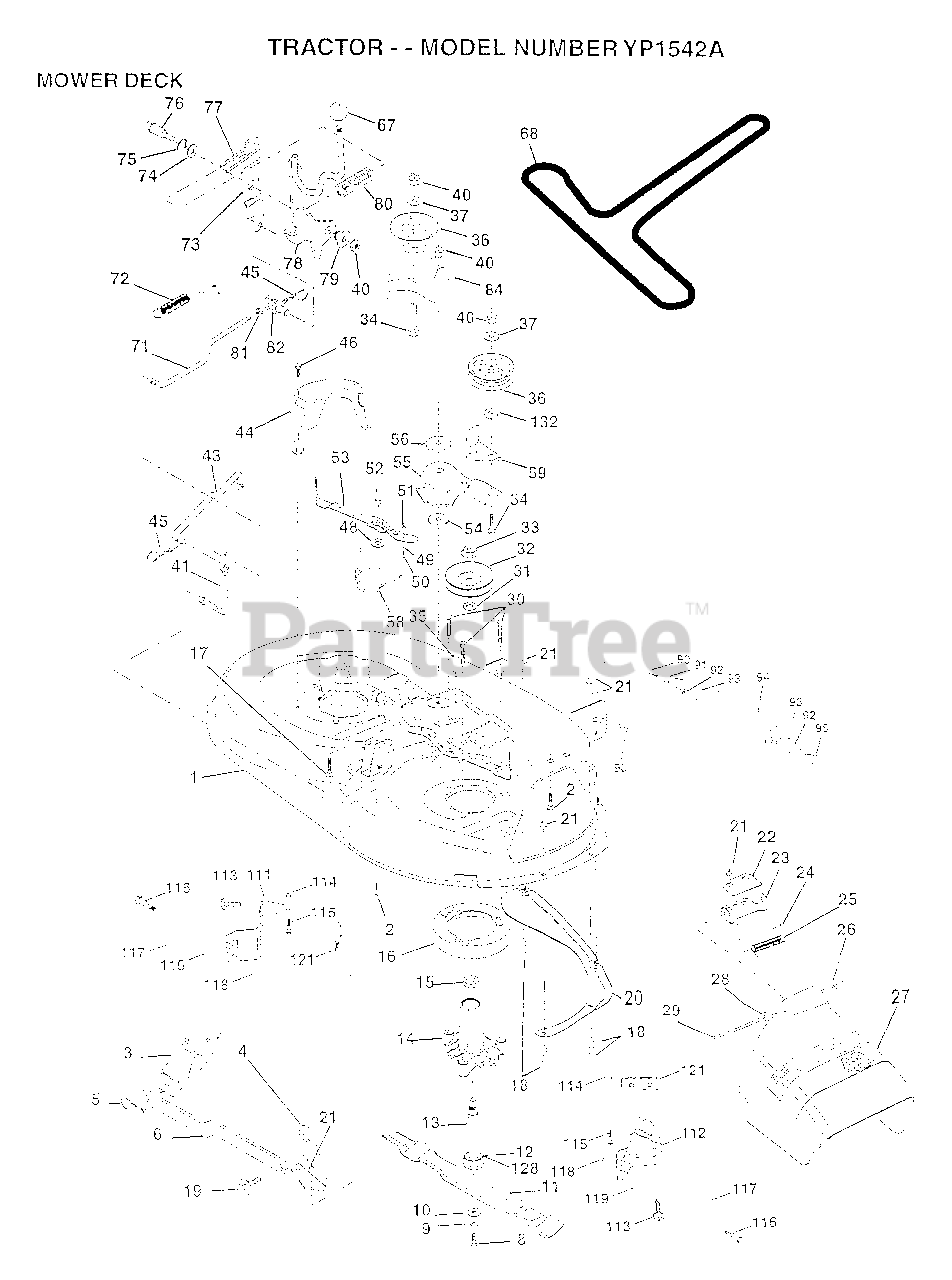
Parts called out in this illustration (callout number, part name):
1	DECK.WELD.42.
2	BOLT
3	BRKT ASM SWAY BAR
4	BRKT DECK SW BAR
8	BLADE BOLT
10	WASHER.HARD.BLADE
11	"BLADE.42"" HIPERF"
12	BEARING.BALL
14	HSG ASM MANDREL
15	BEARING
16	STRIPPER RND MWR
17	BOLT RDHD 3/8-16
18	BOLT
19	BOLT SHD 5/16-18
22	STIFFENER BRKT
23	DEFLECTOR BRKT
24	CAP-SLEEVE LT
25	SPRING TORSION
26	NUT PUSH M
27	DEFLECTOR.SHIELD
28	WASHER
29	HINGE ROD
31	WASHER
32	PULLEY.MANDREL.42
34	BOLT
35	XMAS TREE FASTNER
36	FLAT IDLER PULLEY
37	WASHER
41	PIVOT ROD
43	ROD CLUTCH W/NIBS
44	GUARD MAND LH BLK
45	RETAINER M
46	SCREW.1/4-20X5/8
48	HARD SMALL WASHER
49	ROLLER ASM-CAM
50	SHOULDER BOLT
51	LOCKNUT
52	BOLT.SHLD.5/16-18
54	HARDENED WASHER
55	ARM-IDLER
56	SPACER RETAINER
58	SPRING TORSN BRAK
59	GUARD IDLER TUV
67	KNOB.DUCKHEAD.1/2
68	BELT-V.SEC.46.KEL
71	ROD CLUTCH 38/42
72	RETURN SPRING
73	CLUTCH ARM SECOND
74	WASHER
75	RING
76	SHOULDER BOLT
77	SPRING KEEPER
78	LEVER CLUTCH ASM
79	BUSHING
80	SPRING.CLUTCH.MWR
81	NUT
82	TRUNION ADJ
84	BRACKET ASM IDLER
90	BOLT
92	NUT
93	WASHER
111	BRACKET.GWHL.LH.
112	BRACKET.GWHL.RH.
113	SCREW
116	BOLT.SHOULDER
117	WHEEL GAGE DONUT
118	LOCKNUT
119	WASHER
121	BRACKET.EXTRD.GWL
128	WASHER.FELT.
132	WASHER GT
